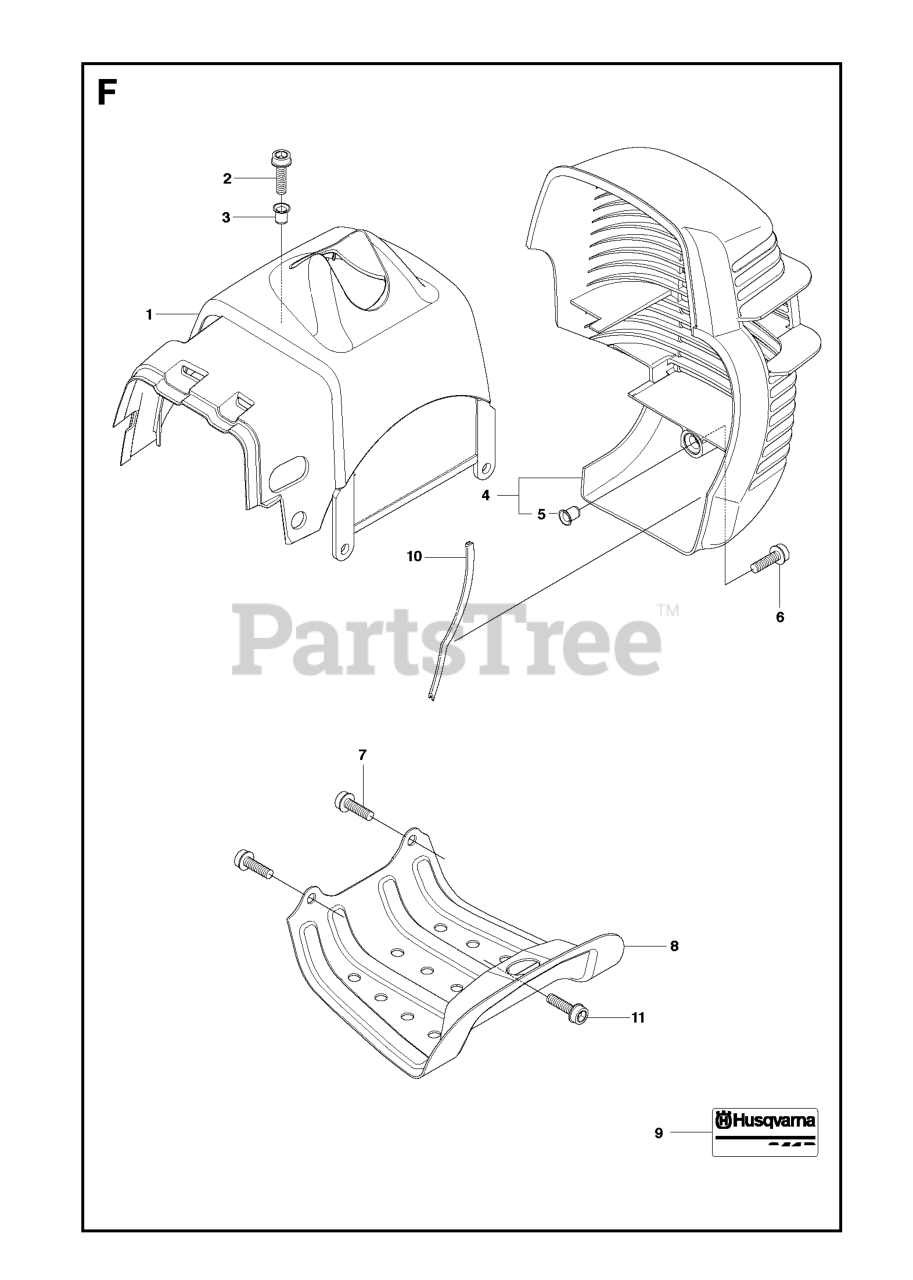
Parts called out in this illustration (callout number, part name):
2	SCREW IHSCFM
4	PROTECTOR
6	SCREW IHSCFM
11	%SCREW
